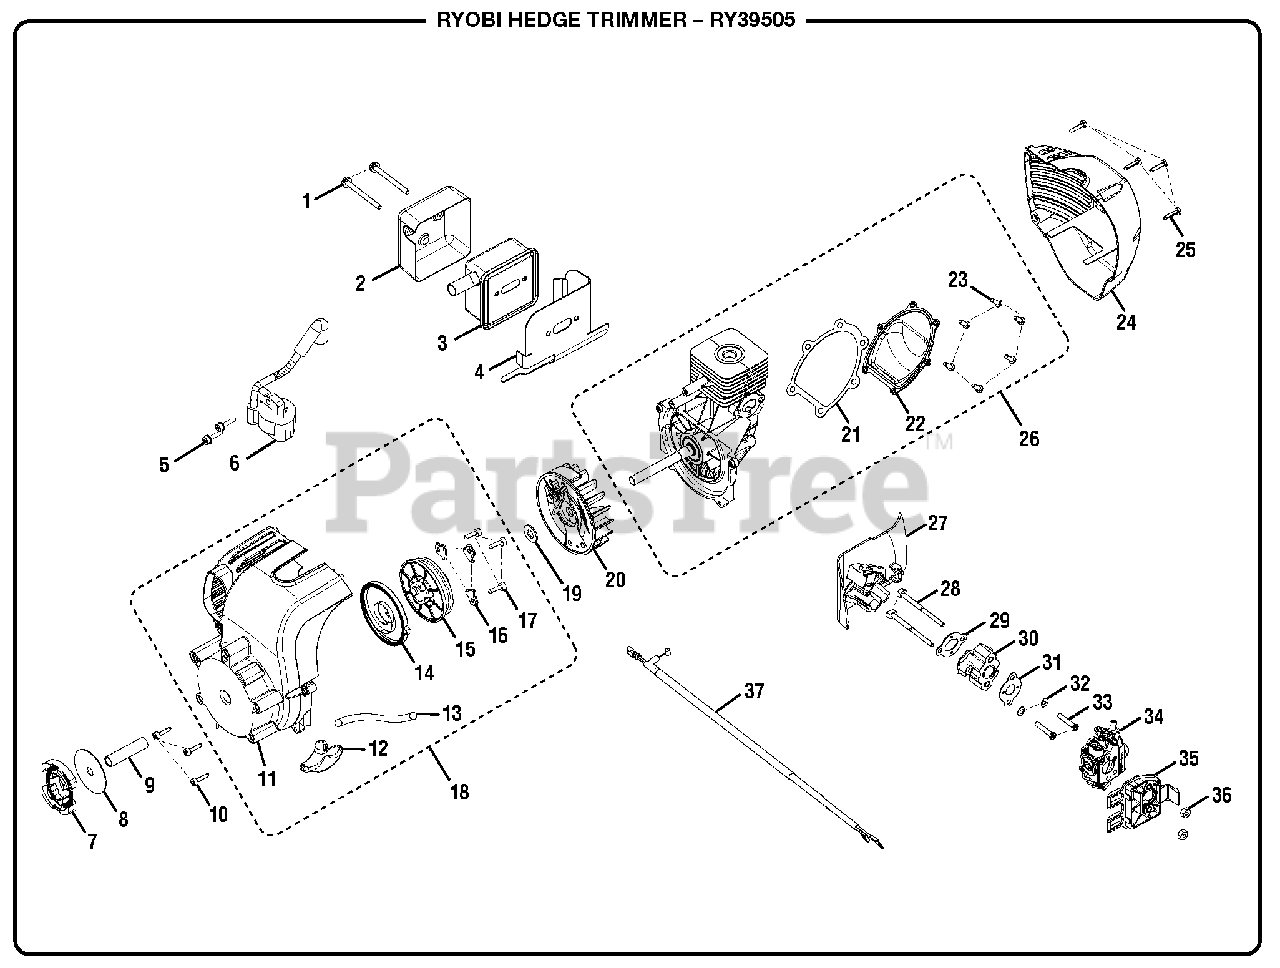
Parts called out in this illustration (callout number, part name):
1	Screw (10-24 x 2-1/8 in.)
2	Heat Shield (Muffler)
3	Muffler Assembly
4	Muffler Gasket
5	Screw (M4 x 19 mm)
6	Ignition Module
7	Clutch Assembly
9	Spacer Tube
10	Screw (M4 x 16 mm)
11	Lower Housing
12	Starter Grip
13	Starter Rope
14	Spring & Container Assembly
15	Starter Pulley
16	Pulley Retainer
17	Screw (M4 x 14 mm)
18	Lower Housing Start Assembly
19	Washer
20	Flywheel Assembly
21	Crankcase Cover Gasket
22	Crankcase Cover
23	Screw (M4 x 12 mm)
24	Upper Housing
25	Screw (M4 x 18 mm)
26	Short Block Assembly
27	Baffle Plate
28	Screw (M5 x 25 mm)
29	Intake Gasket
31	Heat Dam Gasket
33	Screw (M5 x 58 mm)
34	Carburetor
35	Air Box Base
36	Hex Nut (10-24)
37	Throttle Cable And Lead Wire Assembly
